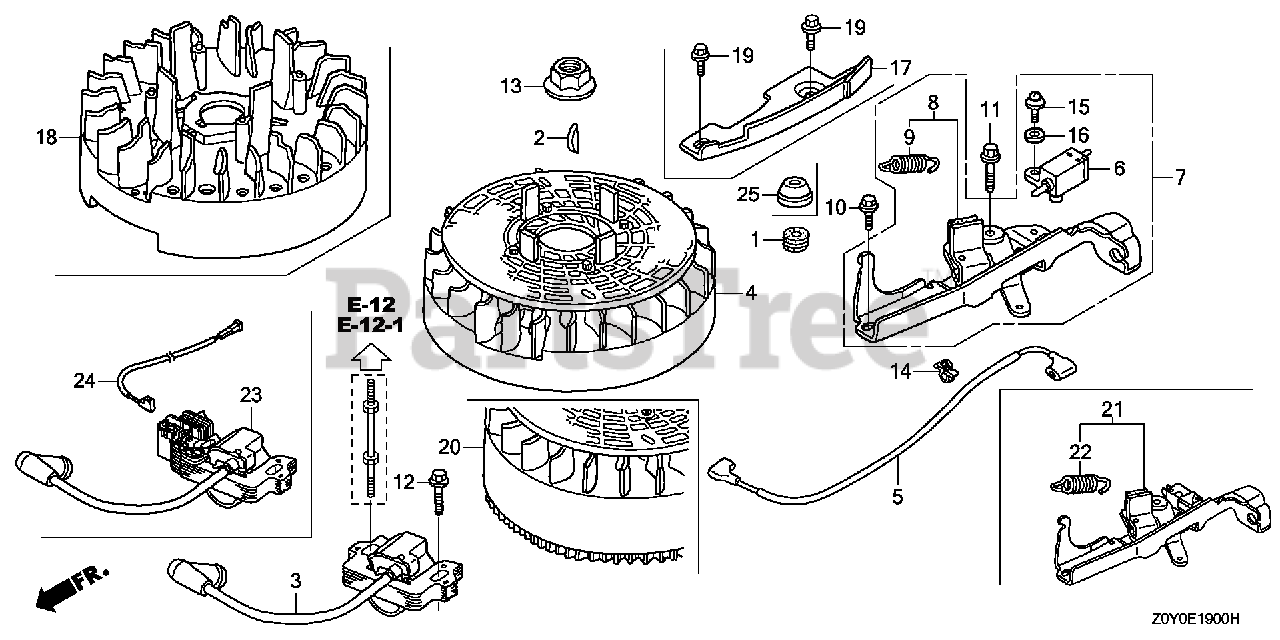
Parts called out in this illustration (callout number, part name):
2	KEY, SPECIAL WOODRUFF (25X18)
3	COIL ASSY., IGNITION (PHELON) (USE FOR F/W OF PHELON)
12	BOLT, FLANGE (6X20) (CT200)
13	NUT, FLANGE (14MM)
14	CLIP, CABLE (A)
17	PLATE, SIDE
18	FLYWHEEL COMP. (PHELON) (USE FOR IGN. COIL OF PHELON) (USE FOR PHELON IGNITION COIL)
19	BOLT, FLANGE (6X12) (CT200)
